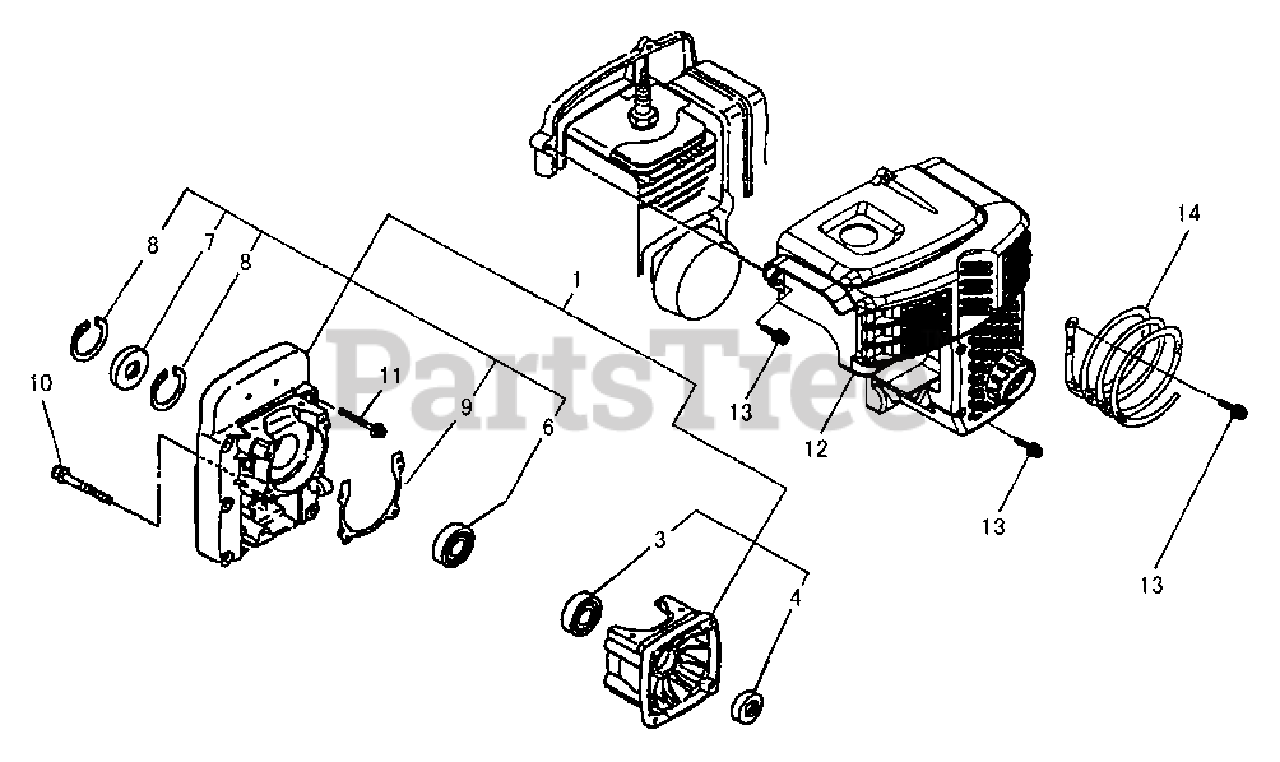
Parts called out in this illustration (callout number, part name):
1	CRANKCASE ASSY
3	BEARING, BALL
4	SEAL, OIL
6	BEARING, BALL
7	SEAL, OIL
8	RING, RETAINING
9	GASKET
10	SCREW - 5X30
11	SCREW - 6X40
12	COVER, ENGINE
13	BOLT - 5X20
14	LEAD - ANTI-STATIC
